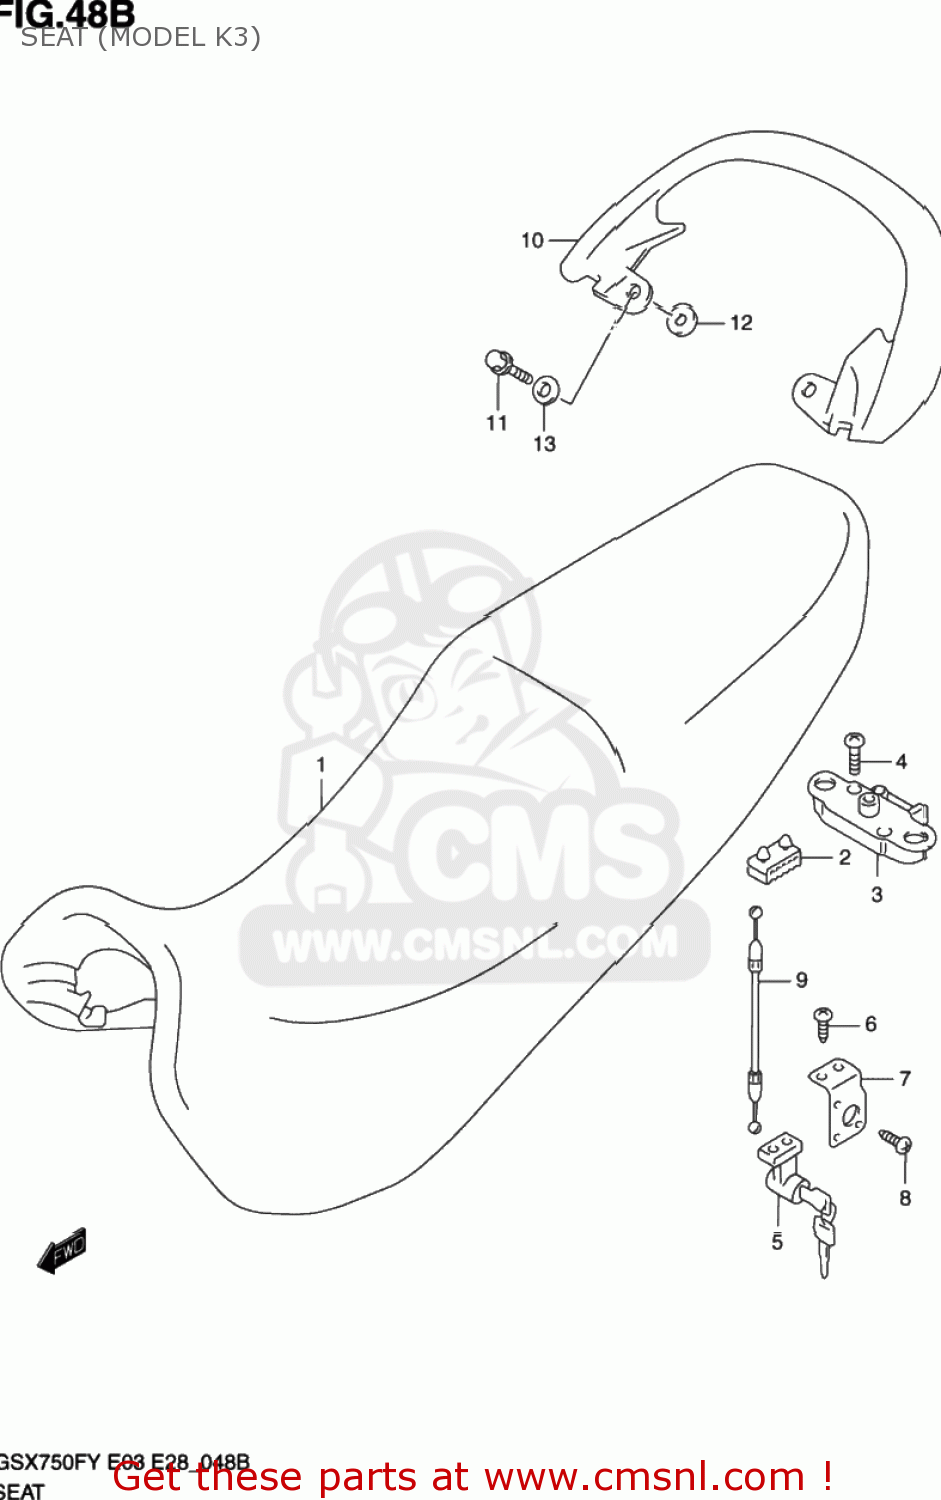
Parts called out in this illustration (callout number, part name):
1	SEAT ASSY
2	CUSHION,SEAT(40X20X15)
3	BRACKET,SEAT SUPPORT,RIGHT
4	SCREW
5	LOCK SET,SEAT
6	BOLT
7	BRACKET,SEAT LOCK
8	SCREW
9	CABLE,SEAT LOCK
10	HANDLE,PILLION RIDER
11	BOLT.MUF SPRT F
12	CUSHION,RIDER HNDL(17X24X1.5)
13	WASHER(8.5X24X2.3)
